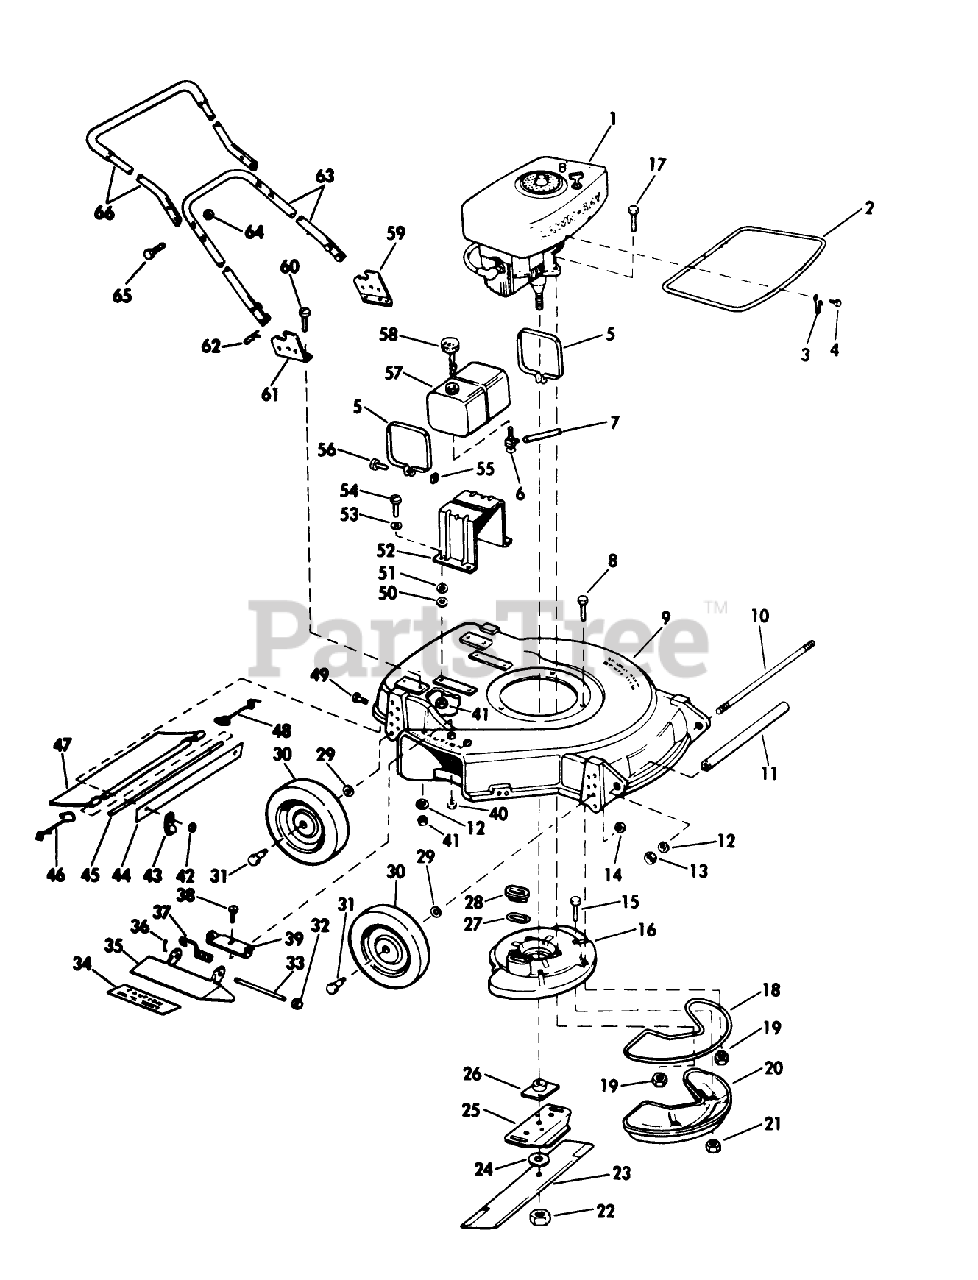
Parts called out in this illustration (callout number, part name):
6	VALVE&SCREEN SM
8	SCREW
12	WASHER WROUGHT
13	LOCKNUT
14	NUT
15	SCREW
19	NUT-LOCK F
22	NUT-BLADE
24	WASHER
26	PLATE AND COLLAR ASM
27	GASKET S
28	SLEEVE
29	WASHER, LOCK
33	HINGE PIN
36	Cotter Pin
38	Screw
40	LOCKNUT E
41	LOCKNUT E
42	LOCKNUT E
46	SPRING;TRAILING SHIELD RH
48	SPRIG T/SHLD ASOC
49	Screw
50	WASHER
54	BOLT PIONEER
55	Nut
60	SCREW S
64	LOCKNUT E
65	SCREW
